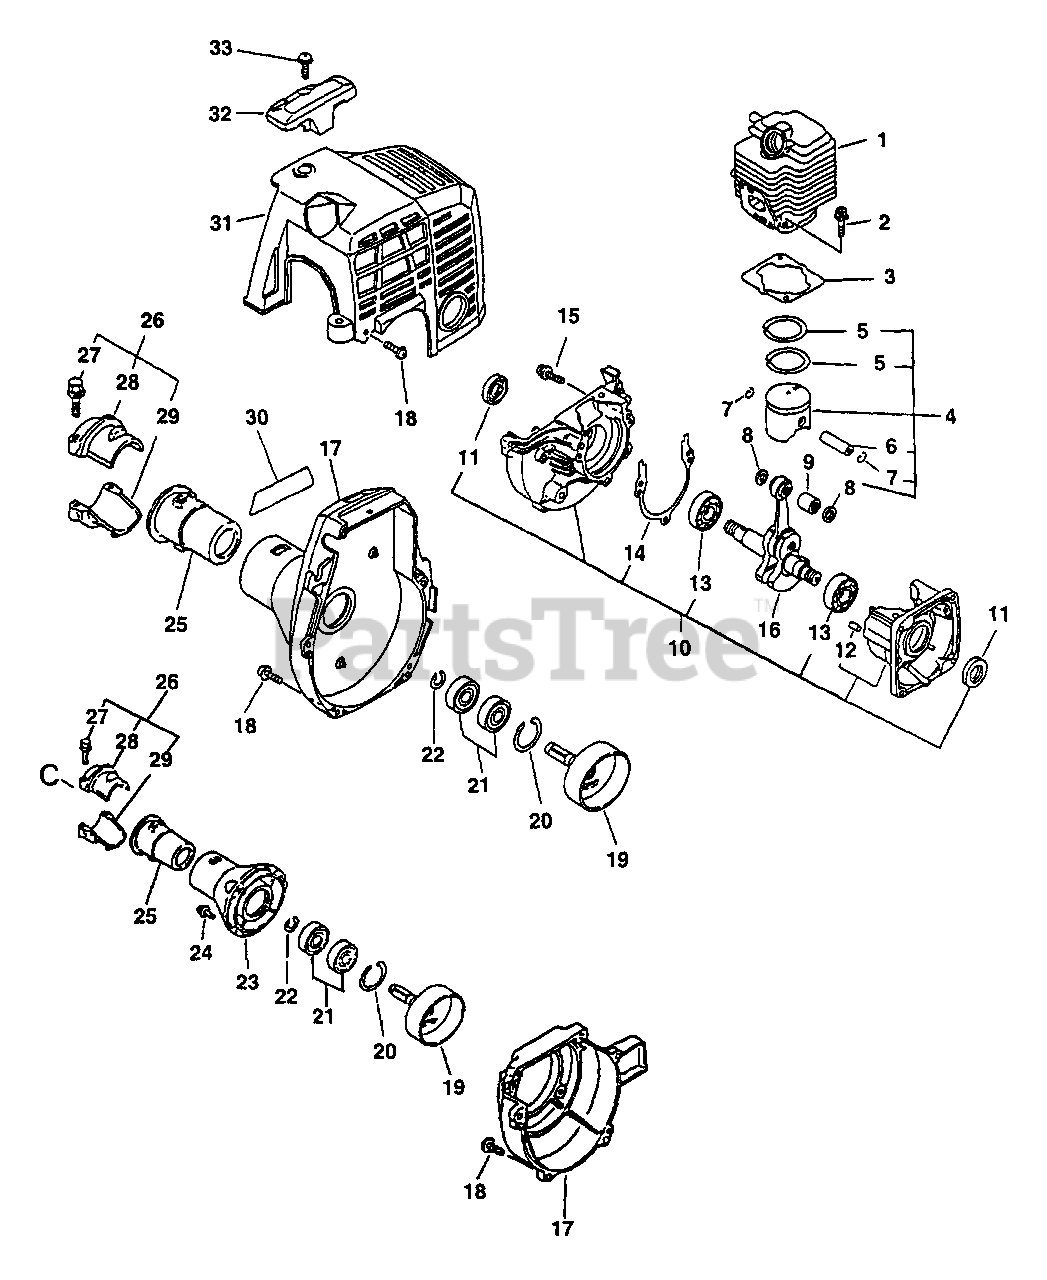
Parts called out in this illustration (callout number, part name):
1	CYLINDER
2	SCREW - 5X22
3	GASKET, CYLINDER
4	PISTON KIT
5	RING, PISTON
6	PIN, PISTON
7	RING, RETAINING
8	SPACER, PISTON
9	BEARING, NEEDLE
10	CRANKCASE KIT
11	SEAL, OIL
12	PIN - LOCATING
13	BEARING, BALL - 6201
14	GASKET, CRANKCASE
15	SCREW - 5X28
16	CRANKSHAFT ASSY
17	CASE, FAN - GRAY
17	FAN CASE ASSY
17	CASE, FAN
18	SCREW - 4X16
19	DRUM, CLUTCH
20	RING, RETAINING - 28
21	BEARING, BALL - 6001
22	RING, RETAINING - 12
23	CASE, CLUTCH - GRAY
24	SCREW - 5X16
25	CUSHION
26	HOLDER KIT
26	MAIN PIPE CLAMP KIT
27	BOLT - 5X25
28	CLAMP, MAIN PIPE - UPPER
29	CLAMP, MAIN PIPE
29	CLAMP, MAIN PIPE - LOWER
30	LABEL - MODEL
31	COVER, ENGINE - GRAY
31	COVER, ENGINE
32	GUARD - TOP
33	SCREW - 5X16
